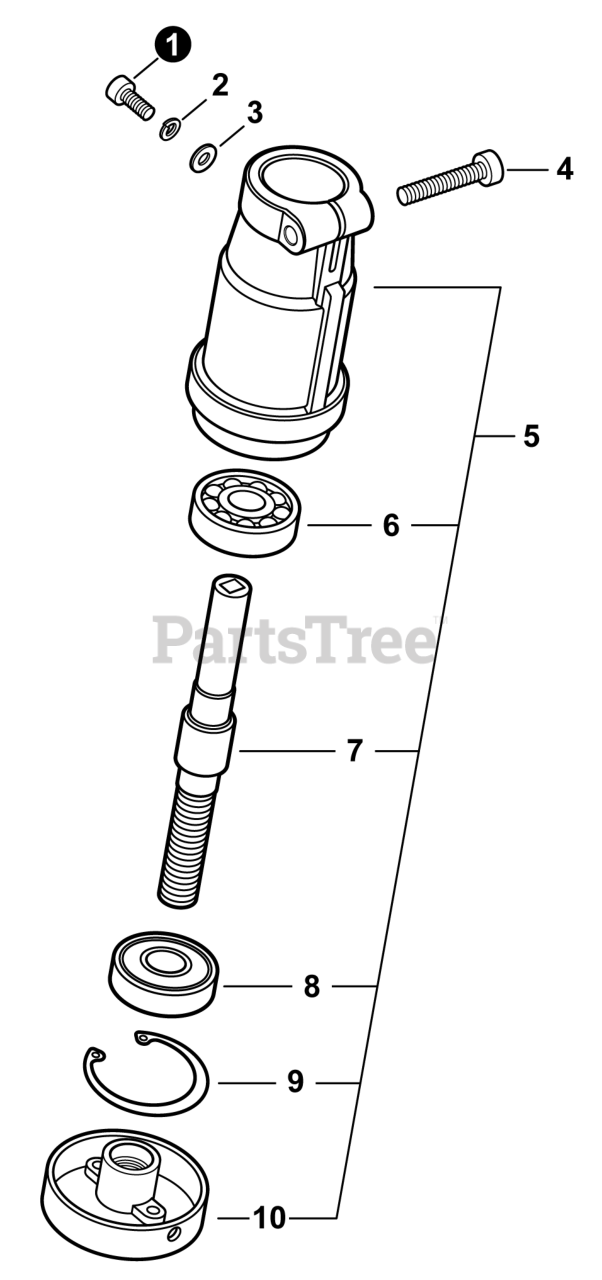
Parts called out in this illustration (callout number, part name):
1	BOLT, TORX 4x10
2	WASHER, SPRING 4 MM
3	WASHER 4 MM
4	BOLT, TORX 5x25
5	GEAR CASE ASSY
6	BEARING, BALL 6200
7	SHAFT, GEAR
8	BEARING, BALL 6200
9	E-RING 30
10	PLATE, ADAPTOR - UPPER
